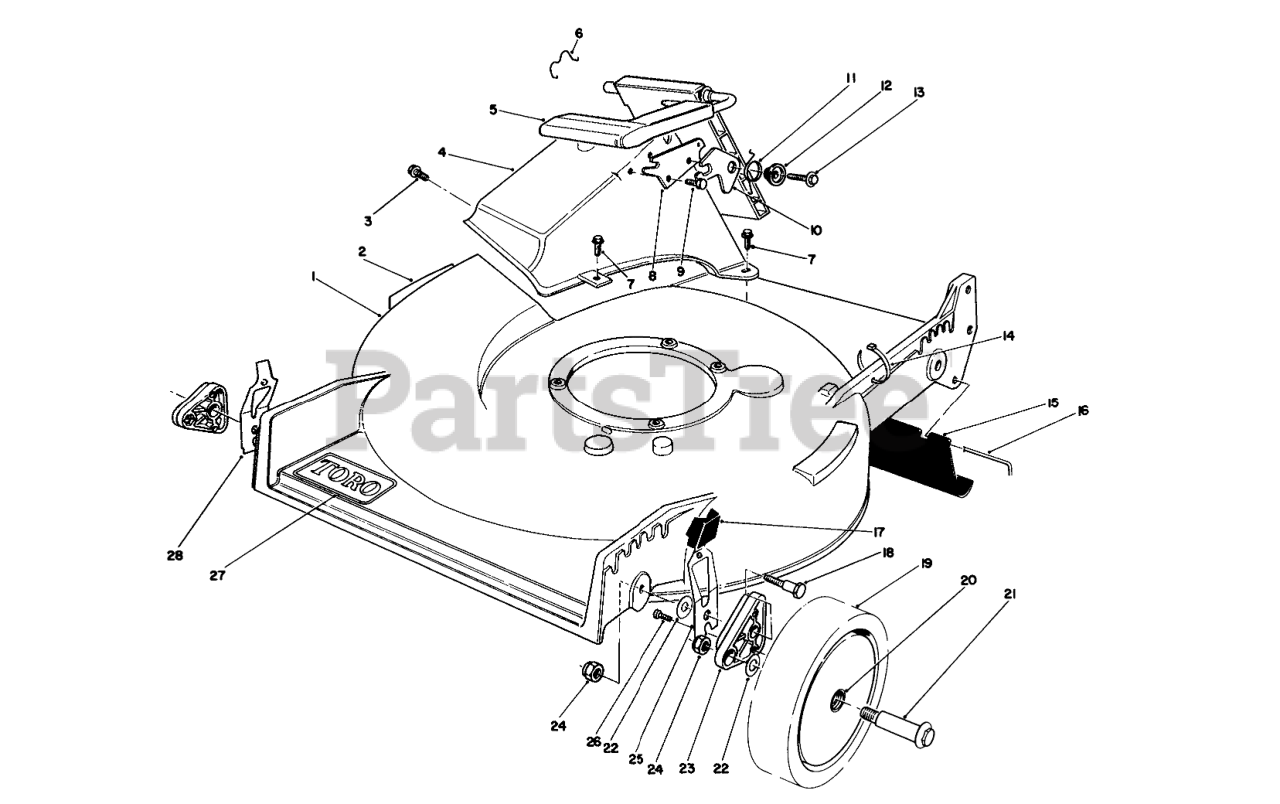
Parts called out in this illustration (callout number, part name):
1	Housing (Incl. Ref. #2)
2	DECAL-DANGER
3	SCREW AND WASHER ASM
4	Tunnel-Discharge
5	Discharge Door Assembly
6	DOOR RET SPRING
7	SCREW-HWH
8	DOOR LATCH PLATE
9	SCREW-PLASTITE
10	SAFETY LATCH
11	TORSION SPRING
12	DOOR SPACER
13	SCREW-HWH
14	TIE-CABLE
15	SHIELD-TRAILING
16	ROD-SHIELD
17	KNOB-ARM
18	SCREW-SHOULDER
19	Wheel & Tire Assembly (Incl. Ref. #20)
20	BUSHING
21	WHEEL BOLT
22	WASHER
23	ARM-PIVOT, FRONT
24	Nut
25	LH SPRING ARM ASSEMBLY
26	SCREW-HWH
27	DECAL
28	RH SPRING ARM ASSEMBLY
